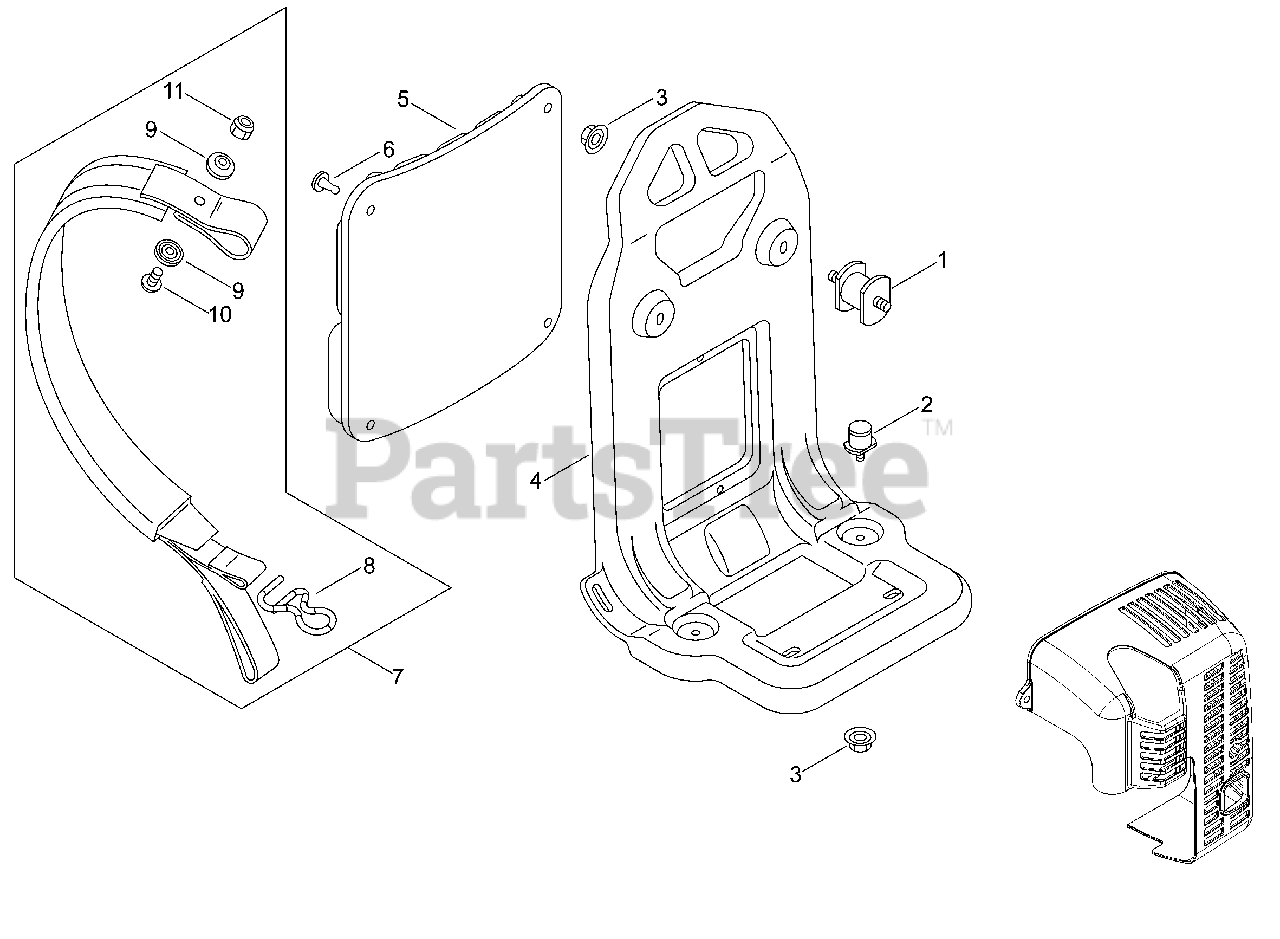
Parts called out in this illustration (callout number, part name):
1	CUSHION 6
2	CUSHION 6
4	FRAME, BACKPACK
5	CUSHION, BACKPACK
7	HARNESS ASSY, BACKPACK
8	RING, HARNESS
9	WASHER 5.2×22×2.0
10	SCREW 5×16
11	NUT, LOCK M5
